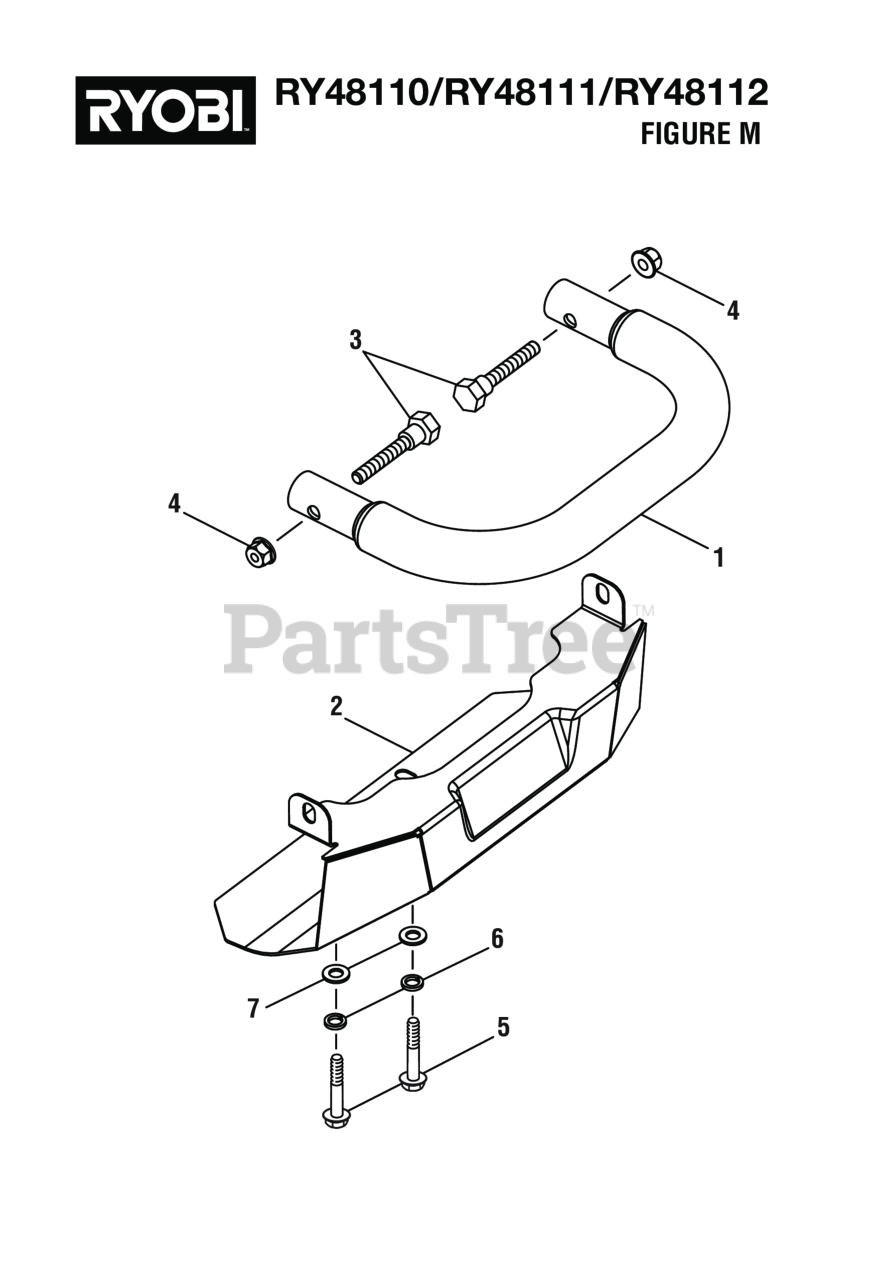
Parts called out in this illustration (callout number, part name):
1	Mower Bumper Tube
2	Front Bumper Cover
3	Shoulder Bolt (M8 x 50 mm)
4	Flange Nut (M8) (For Drive Motor Controller V)
5	Shoulder Bolt (M8 x 45 mm, Hex Flange Hd.)
6	Lock Washer (OD9.8 x ID8.5 x 5t)
7	Washer (OD16 x ID8.4 x 1.6t)
